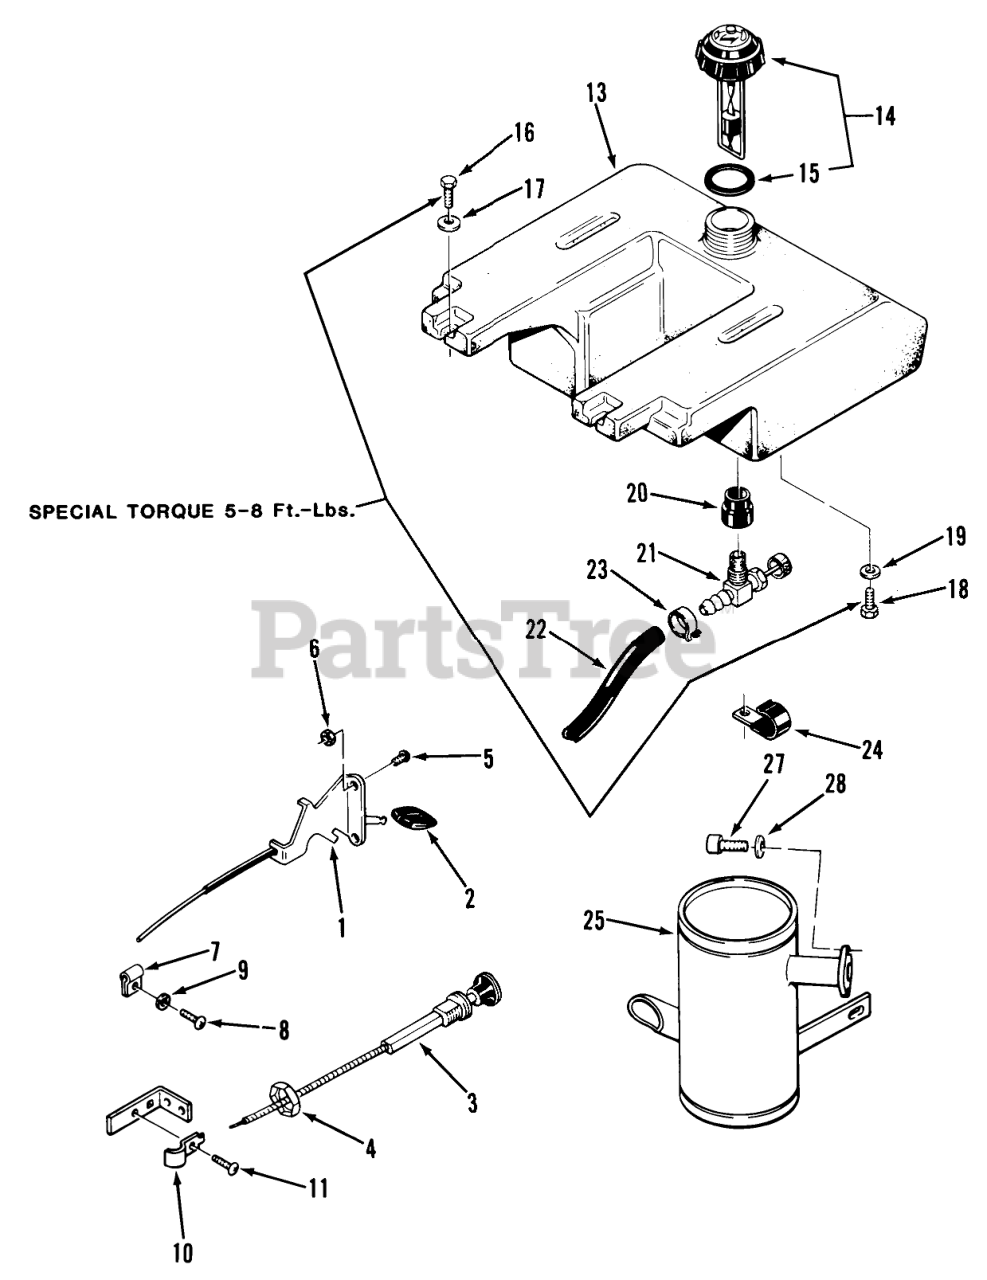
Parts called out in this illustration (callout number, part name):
2	KNOB-THROTTLE
3	CONTROL CHOKE
4	NUT-HEX PALNUT
7	THROTTLE CONTROL CLP
10	CLAMP-CABLE
13	TANK-FUEL
14	ASSY-GAUGE CAP
21	VALVE-FUEL
24	CLAMP
27	SHCS 5/16-18X.750
